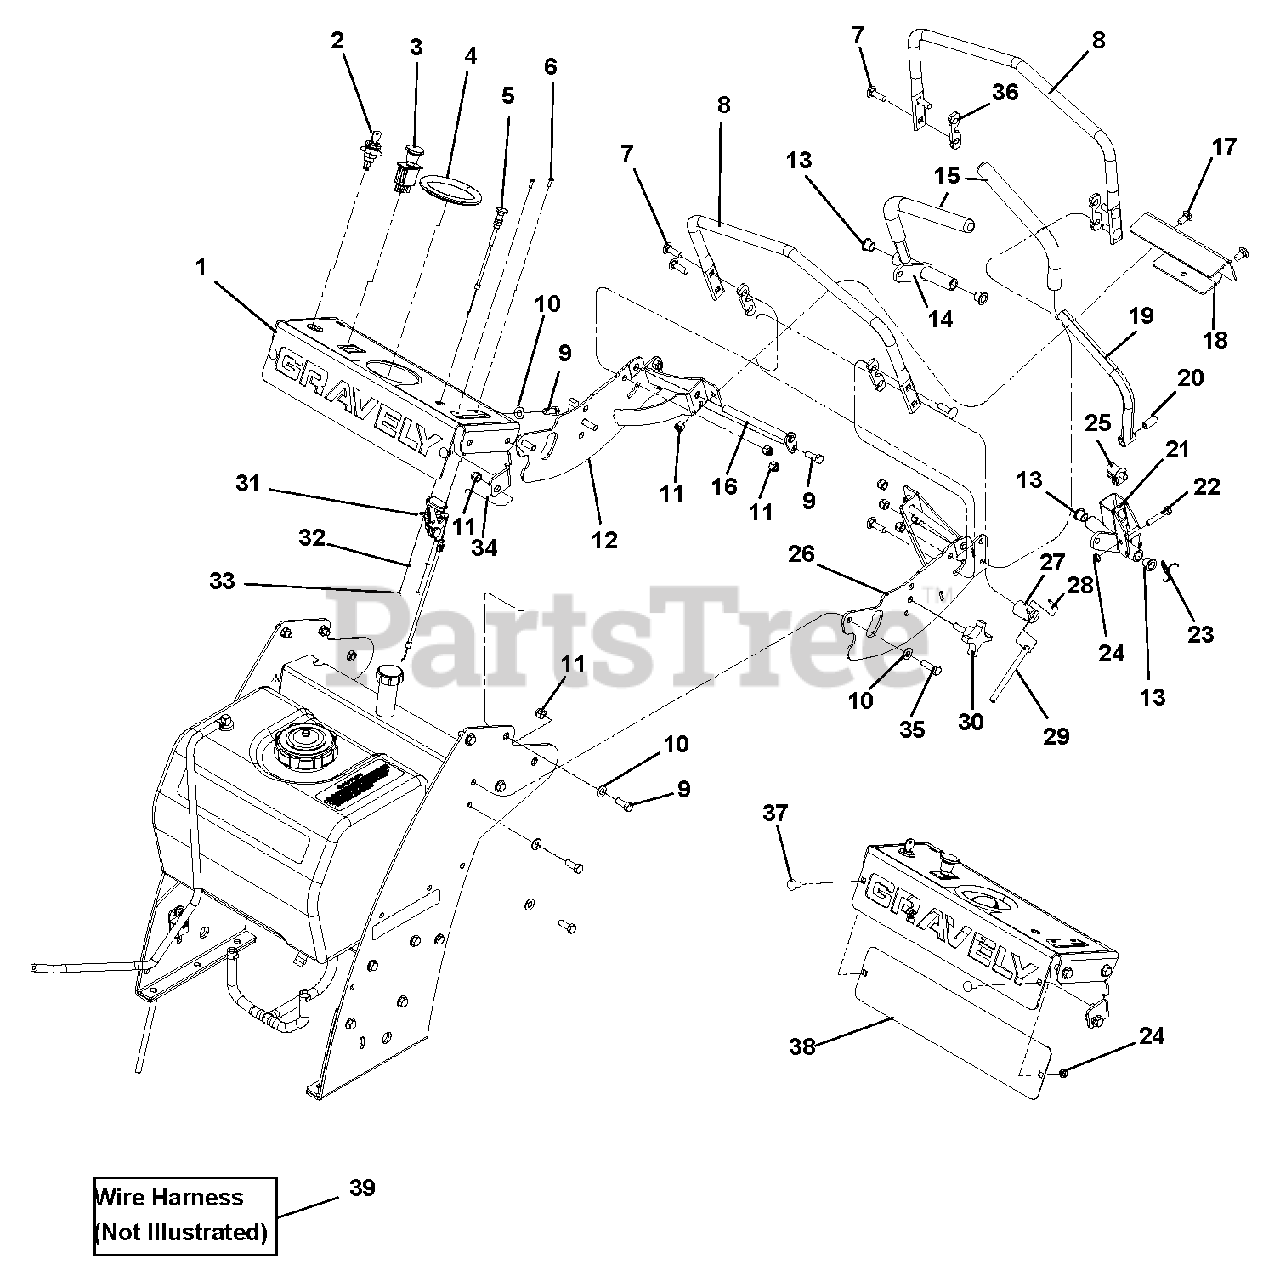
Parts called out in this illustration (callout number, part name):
1	ASSY, CONSOLE W/DECALS
2	SWITCH, TWO POSITION KEY
3	SWITCH, PTO ENGAGEMENT
4	TRIM, RUBBER EDGE 12"
5	CABLE, CHOKE 48"
6	SCREW, 8-32 X 1/2
7	BOLT, RDHDSQNK .38-16 X 1.25 G5
8	Support Handle
9	Bolt-Hex .38-16 x 1.00 Grade 5
10	WASHER, .406 X .813 X .065 FLAT Y
11	LOCKNUT, 3/8-16 NYLOC
12	WLDT, RH CONTROL MOUNT
13	BRG, FLG .500 X .625 X .500 BRNZ
14	WLDT, RH DRIVE LEVER
15	GRIP, CONTROL
16	WLDT, PIN AND LOCK
17	Bolt-Round Head Square Neck .38-16 x .75 Grade 2
18	DRIVE ARM BACK PLATE
19	WLDT, LH DRIVE LEVER
20	SPACER, .330 X .500 X .980
21	WLDT, LH HANDLE MOUNT
22	BOLT, HEX .31-18 X 1.75 GR5 Y
23	Spring, TOR 1.00 X .062 Y
24	LOCKNUT, 5/16-18 NYLOC Y
25	SWITCH, SEAT OVER RIDE (N.O.)
26	WLDT, LH CONTROL MOUNT
27	BASE, LOCK LEVER Y
28	PIN, SPRING
29	LEVER, LOCK
30	KNOB, 3/8 X 1.25 - 4 PRONG
31	CABLE, THROTTLE - 49.5
32	WASHER, #8 MED SPRG LOCK Y
33	NUT, 8-32 STD HEX Y
34	ASSY, HANDLE BRACE
35	BOLT, HEX .38-16 X 1.25 GR5
36	SHIM, 5 DEG SPEED BAR
37	BOLT-RDHDSQNK .31-18X.75 G5
38	PLATE, BACK LASER GRAVELY WLK
